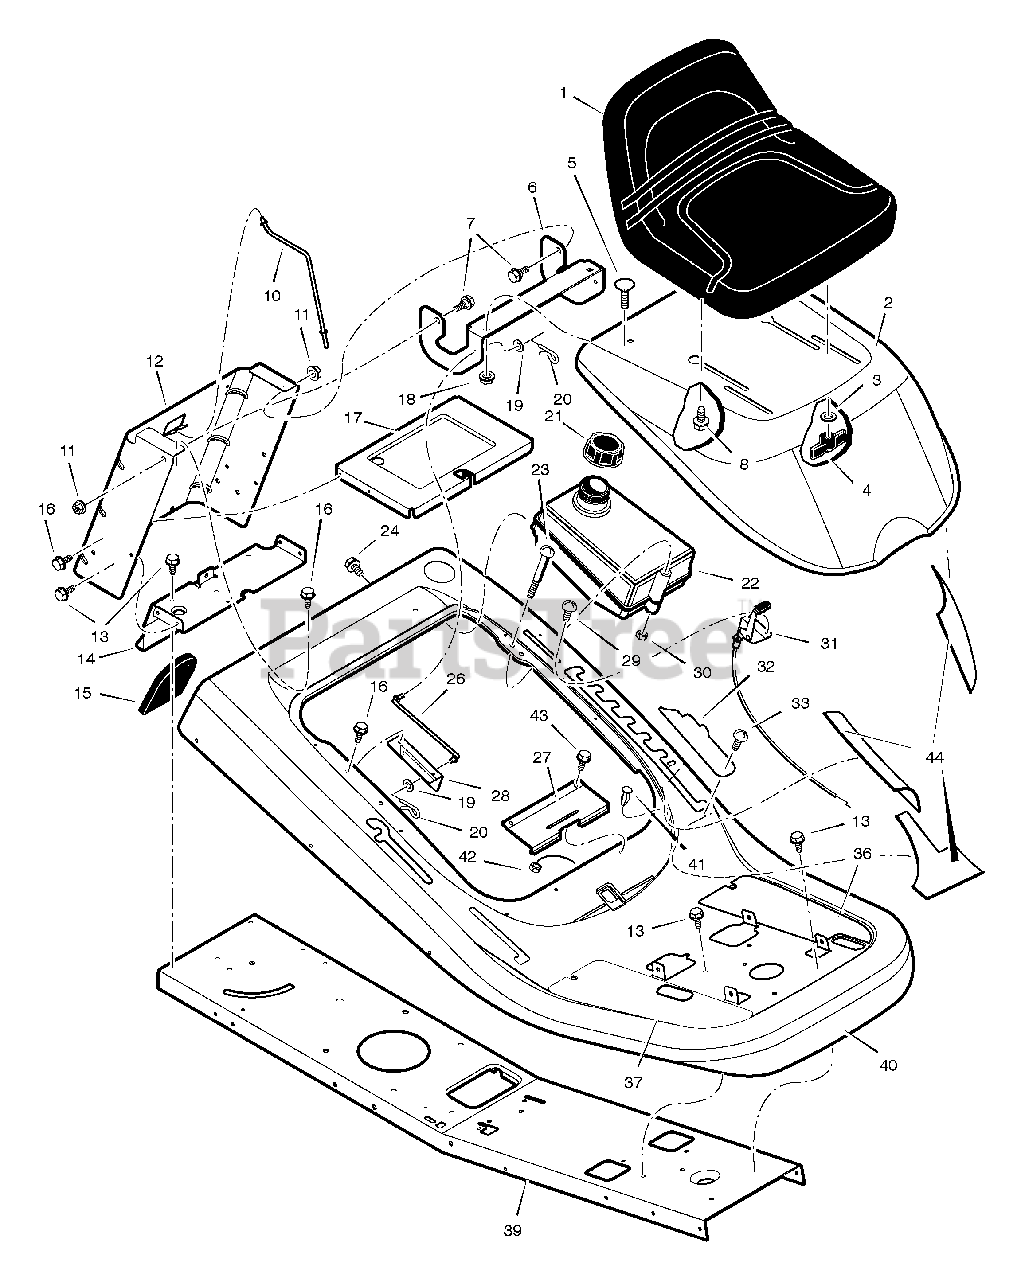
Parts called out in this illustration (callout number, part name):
1	Seat
3	Washer
4	Bolt, Wing
5	Bolt, Carriage
6	Bracket, Hinge
7	Bolt, Shoulder
8	Bolt, Shoulder
10	Rod, Battery
11	Nut, Flange
12	Plate, Rear
14	Plate, Hitch
17	TRAY, Battery
18	Nut, Flange
19	Washer
20	Pin, Cotter
21	Cap, Fuel Tank
22	Tank, Fuel
26	Rod, Hood Prop
27	Spring, Seat Deck
28	Bracket, Prop Rod
30	Nut, NY-Lock
31	Control, Throttle
32	Cover, Detent (Black)
33	Bolt, Shoulder
36	Footmat, Left
37	Footmat, Right
40	Deck, Seat
41	Bumper
42	Nut
43	Screw
44	Kit, Foil Heat Shield
